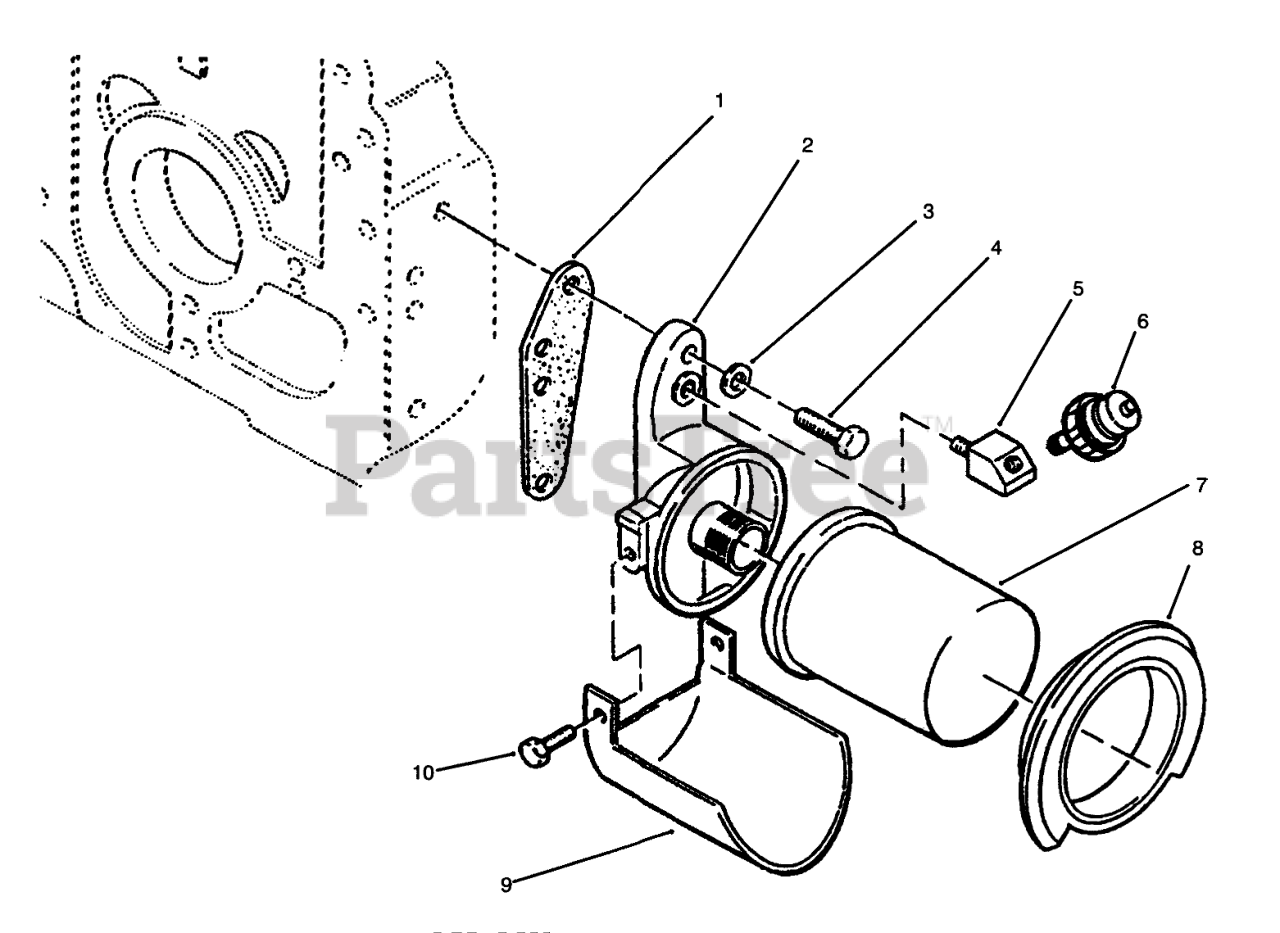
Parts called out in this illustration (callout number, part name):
1	Gasket
2	ADAPTER-OIL FILTER
3	WASHER
4	HHCS 5/16-18 X 1
5	45 DEG STREET ELBOW
6	SWITCH - OIL PRESSURE
7	OIL FILTER
8	GASKET - AIR SEAL
9	OIL-FILTER DRAIN
10	SCREW-HH
